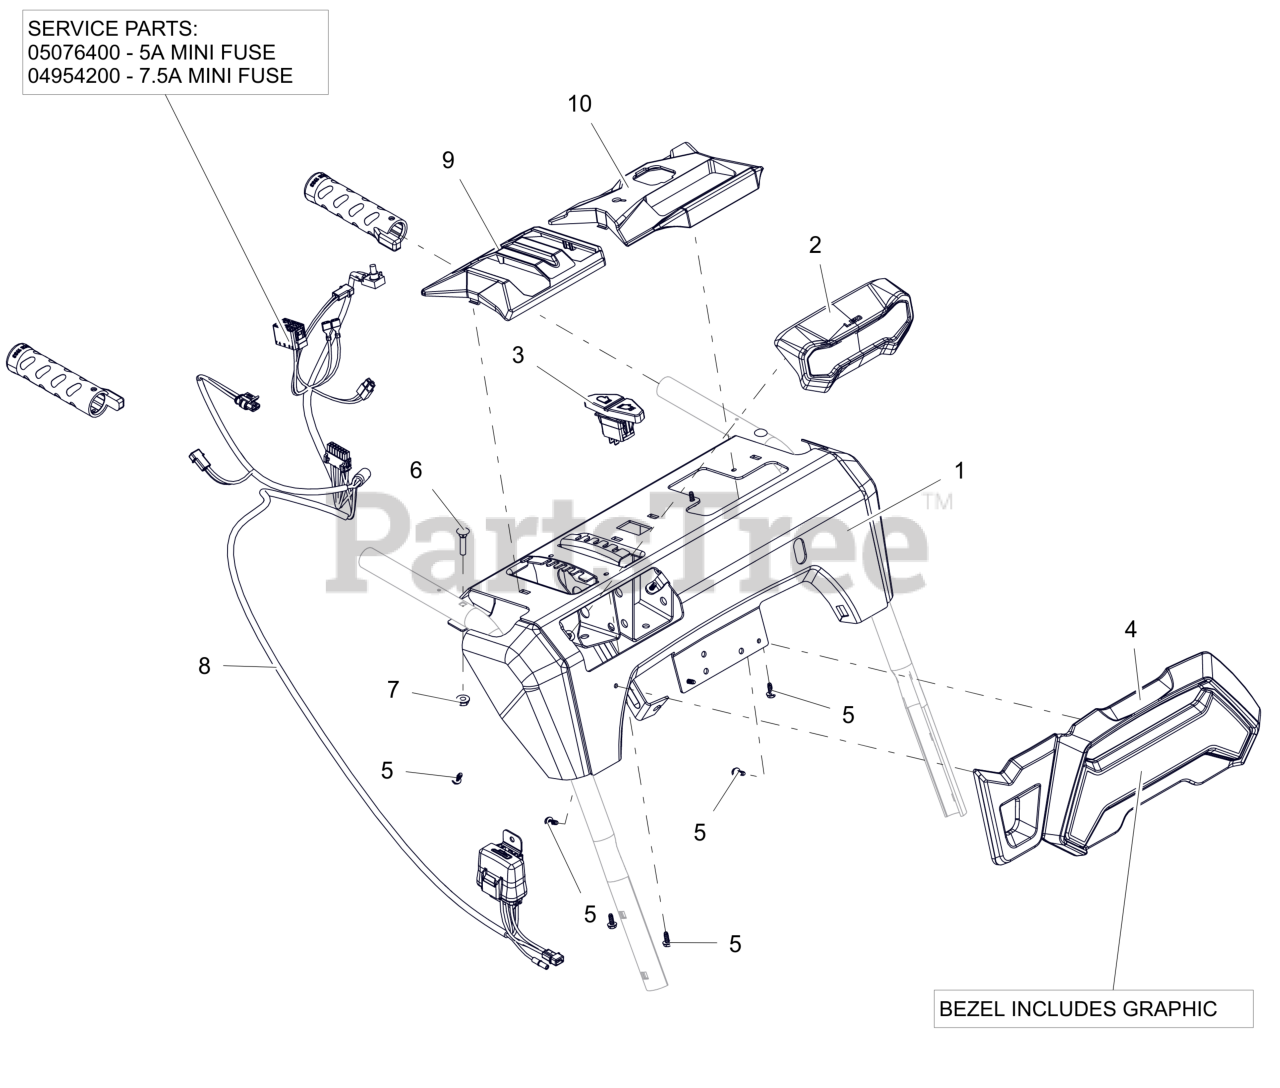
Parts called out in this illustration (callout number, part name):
1	PANEL, CONTROL-EFI ID W/DECAL
2	HEADLIGHT ASM- LED
3	SWITCH- ROCKER SPST-ON/OFF
4	BEZEL- LARGE - PLATINUM
5	SCR, PLASTIC #10X.50
6	BLT-RDHDXLSQNK.25-20X1.25 G5ZC
7	NUT-LK-CTR-FLG .25-20 ZC120
8	HARNESS- WIRE - LT HG EFI
8	FUSE, 5 AMP MINI-ATC
8	FUSE, 7.5 AMP MINI-ATC
9	BEZEL, SHIFT - FRICTION
10	BEZEL, OPERATOR EFI CHUTE DECAL
